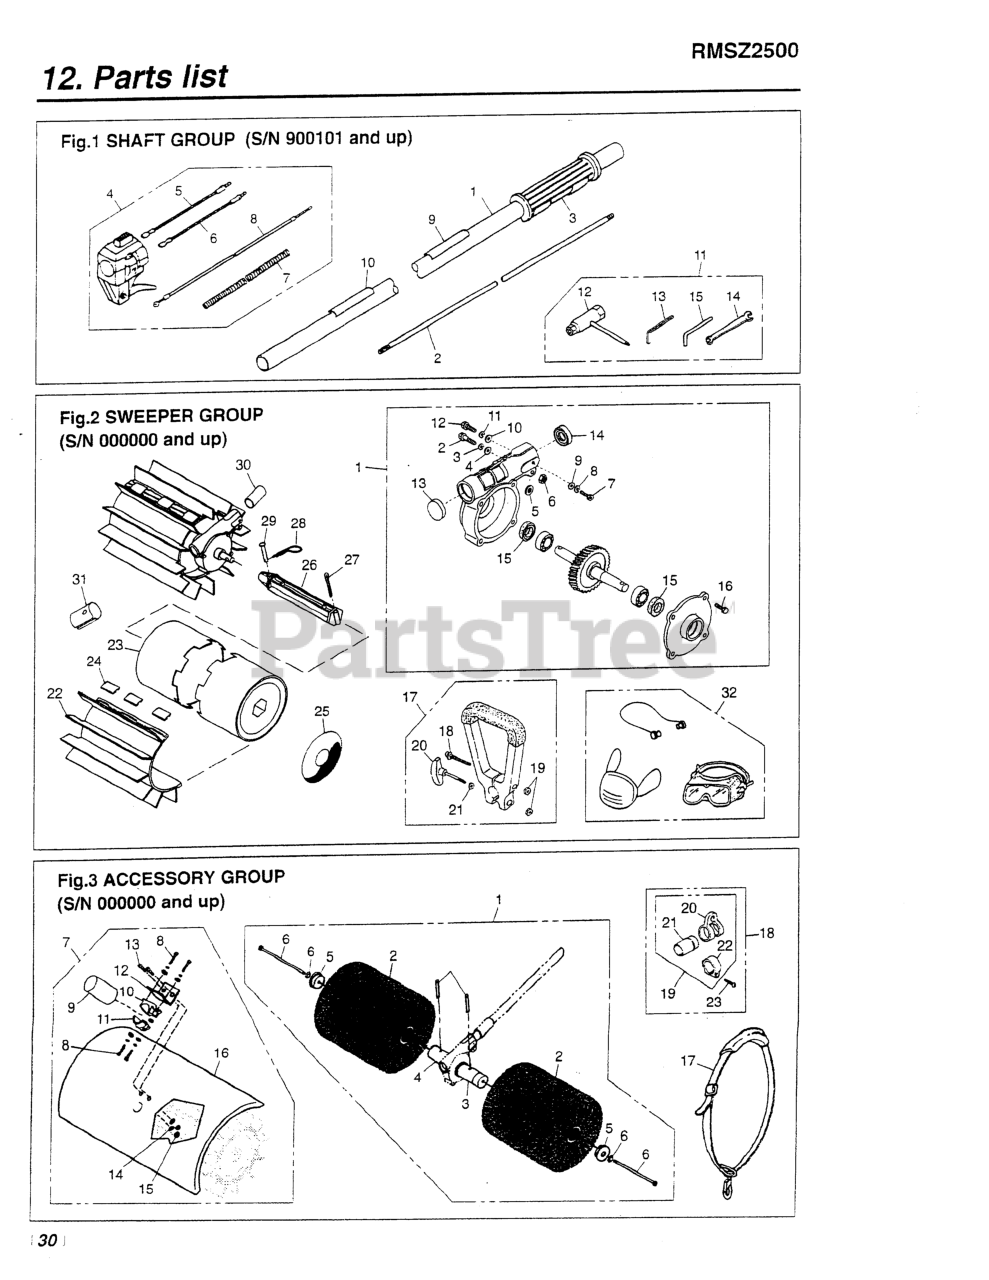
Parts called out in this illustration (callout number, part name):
1-1	PIPE COMPLETE
1-3	GRIP (RPLS 3577-32140 & 3220-
1-5	CORD (A), BLACK
1-6	CORD (B), RED
1-7	TUBE (RPLS 4900-72141)
1-8	CABLE (RPLS 5580-83100)
1-9	NAMEPLATE
1-10	PLATE, CAUTION
1-12	SOCKET
1-13	WRENCH (TOOL)
1-14	SPANNER, 8 X 10 (RPLS 2540- )
1-15	BAR
2-2	BOLT, M6 x 30
2-3	SPRING WASHER
2-4	WASHER, FLAT
2-5	WASHER, FLAT
2-6	NUT, M6 X 5
2-7	BOLT, M5 x 12
2-8	WASHER, SPRING M4 x 1.3
2-11	WASHER, SPRING M4 x 1.3
2-12	SCREW
2-13	PLUG, HOUSING
2-16	SCREW
2-17	HANDLE ASSY (RPLS 99909-33009)
2-24	CLIP, BELT
2-25	LABEL, REDMAX
2-26	AXLE, DRUM (RPLS -33016)
2-27	PIN, COTTER
2-28	PIN, HITCH
2-29	PIN, CLEVIS (RPLS -33018)
2-30	PROTECTOR, TUBE
2-32	SAFETY KIT
3-1	BRUSH SWEEPING ATTACH (NYLON)
3-2	BRUSH, NYLON
3-3	ADAPTOR, GEAR SHAFT, LH
3-4	ADAPTOR, GEAR SHAFT, RH
3-6	KIT, BRUSH HARDWARE
3-7	DEBRIS SHIELD ASSEMBLY
3-10	BRACKET, HANDLE
3-11	CAP, LOWER
3-12	BRACKET, SHIELD
3-18	HANGER ASSEMBLY
3-19	HANGER COMPLETE
3-20	HANGER
3-21	CLAMP
3-22	SLEEVE
3-23	SCREW, M5 x 25
